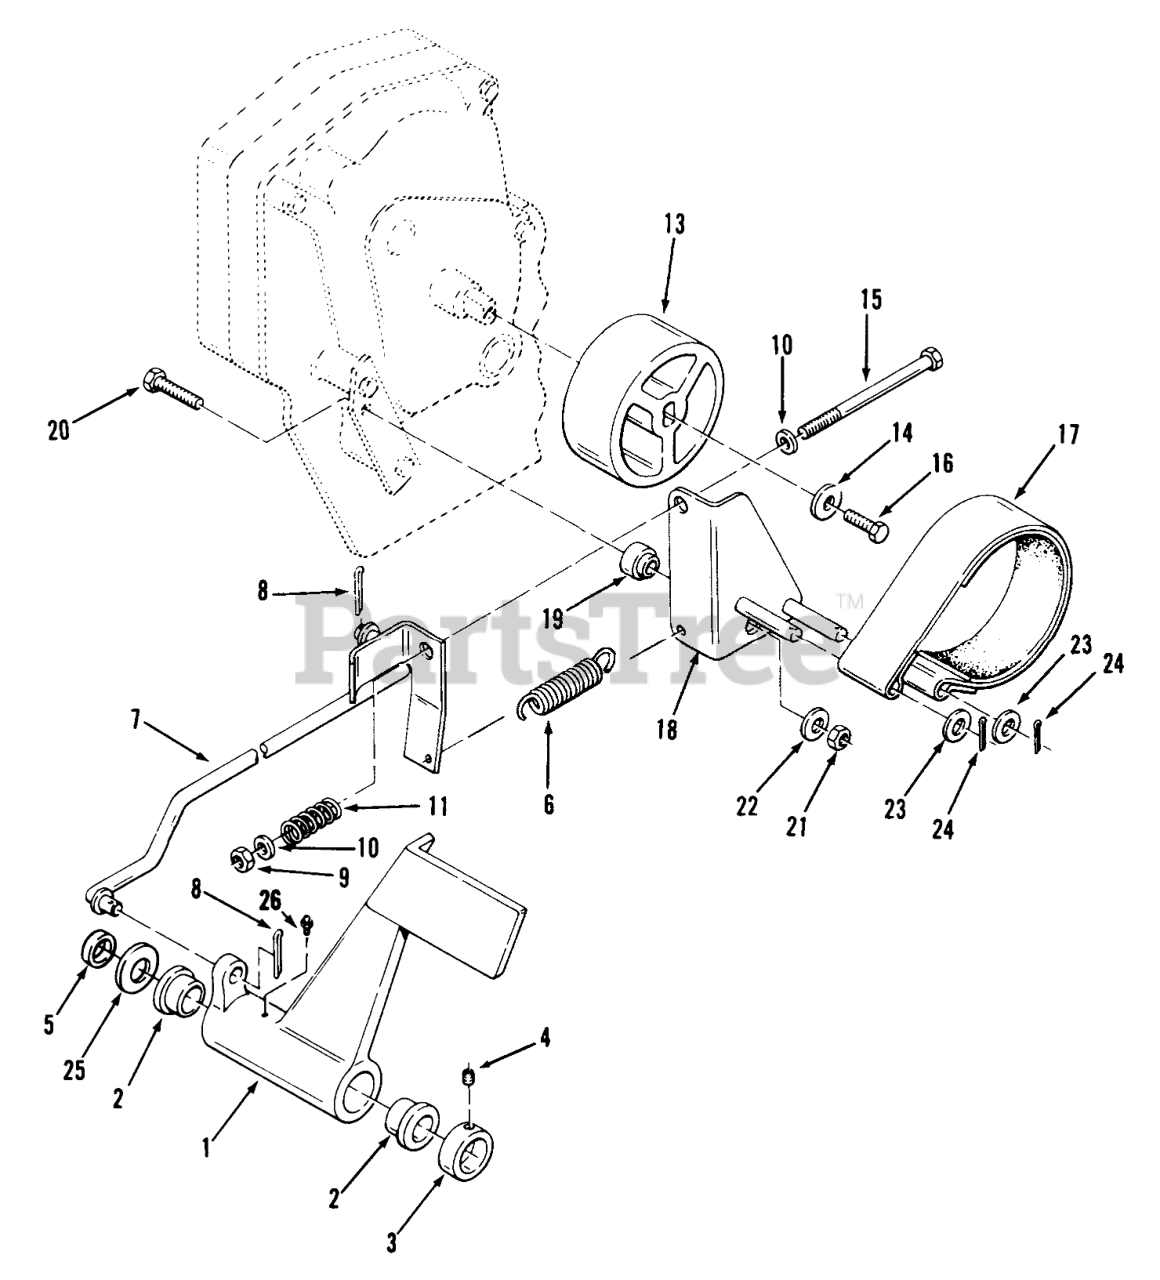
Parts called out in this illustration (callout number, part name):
1	Pedal-Brake
2	BUSHING
3	Collar
4	SCREW-HSH
5	SPACER
6	SPRING
7	ASY BRAK RD WAR
8	PIN-COTTER
9	NUT-LOCK, NI
10	WASHER-FLAT
11	SPRING-COMPRESSION
13	DRUM-BRAKE
14	WASHER
15	SCREW-HH
16	SCREW-HH, LOCK
17	ASSY-BRAKE BAND
18	BRACKET-BRAKEB
19	BUSHING-BRAKE PIVOT
20	SCREW-HH
21	NUT-LOCK, NI
22	WASHER-FLAT
23	WASHER-FLAT
24	PIN-COTTER
25	WASHER
26	Zerk
